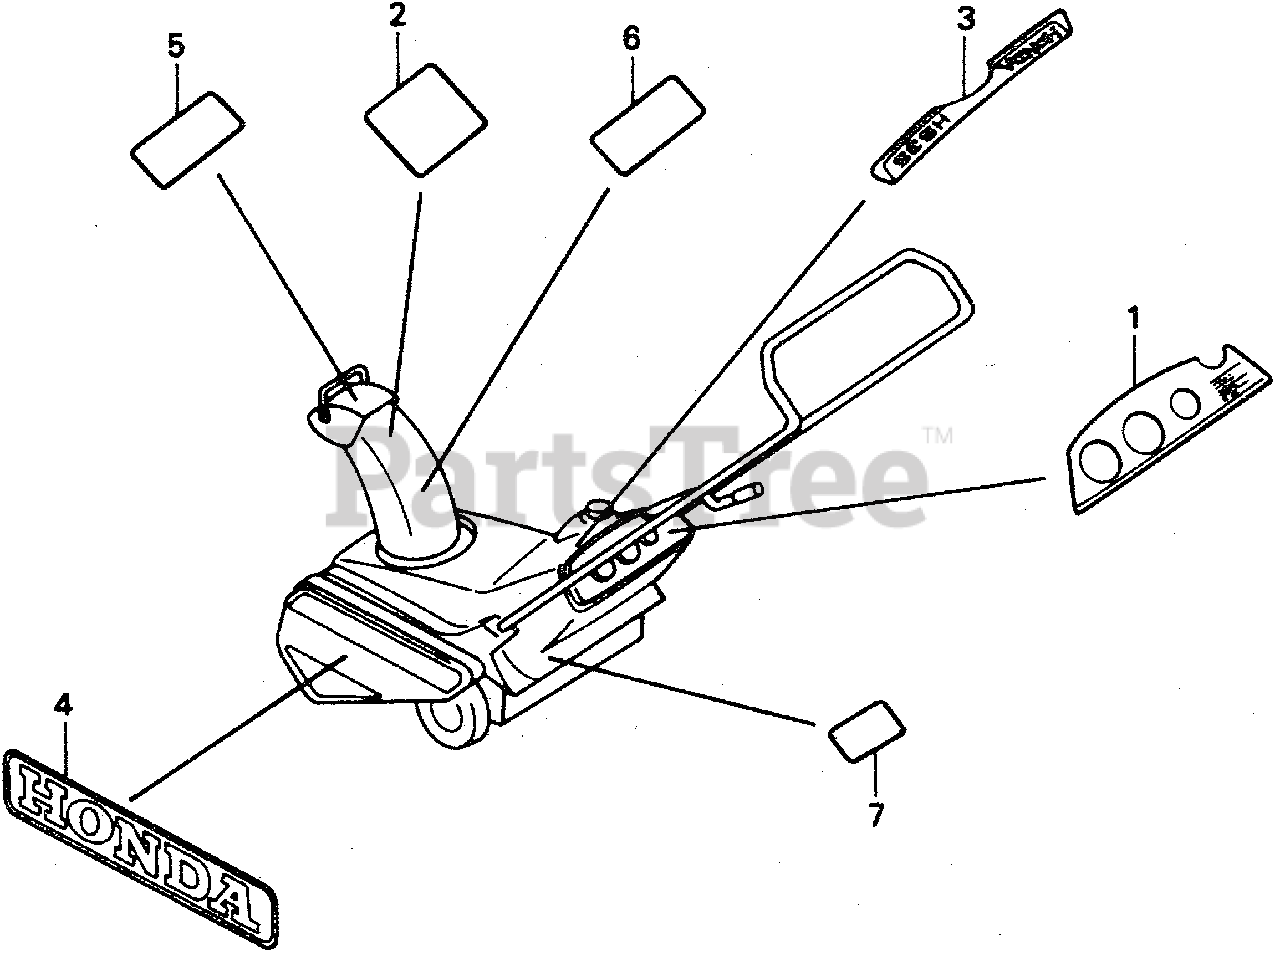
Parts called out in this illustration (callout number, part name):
1	MARK, CONTROL PANEL (ENGLISH)
2	LABEL, WARNING (ENGLISH)
3	EMBLEM, TOP COVER
4	EMBLEM, SIDE
5	MARK, HOUSING DANGER (ENGLISH)
6	MARK, DISCHARGE DANGER (ENGLISH)
7	MARK, OIL CAUTION
